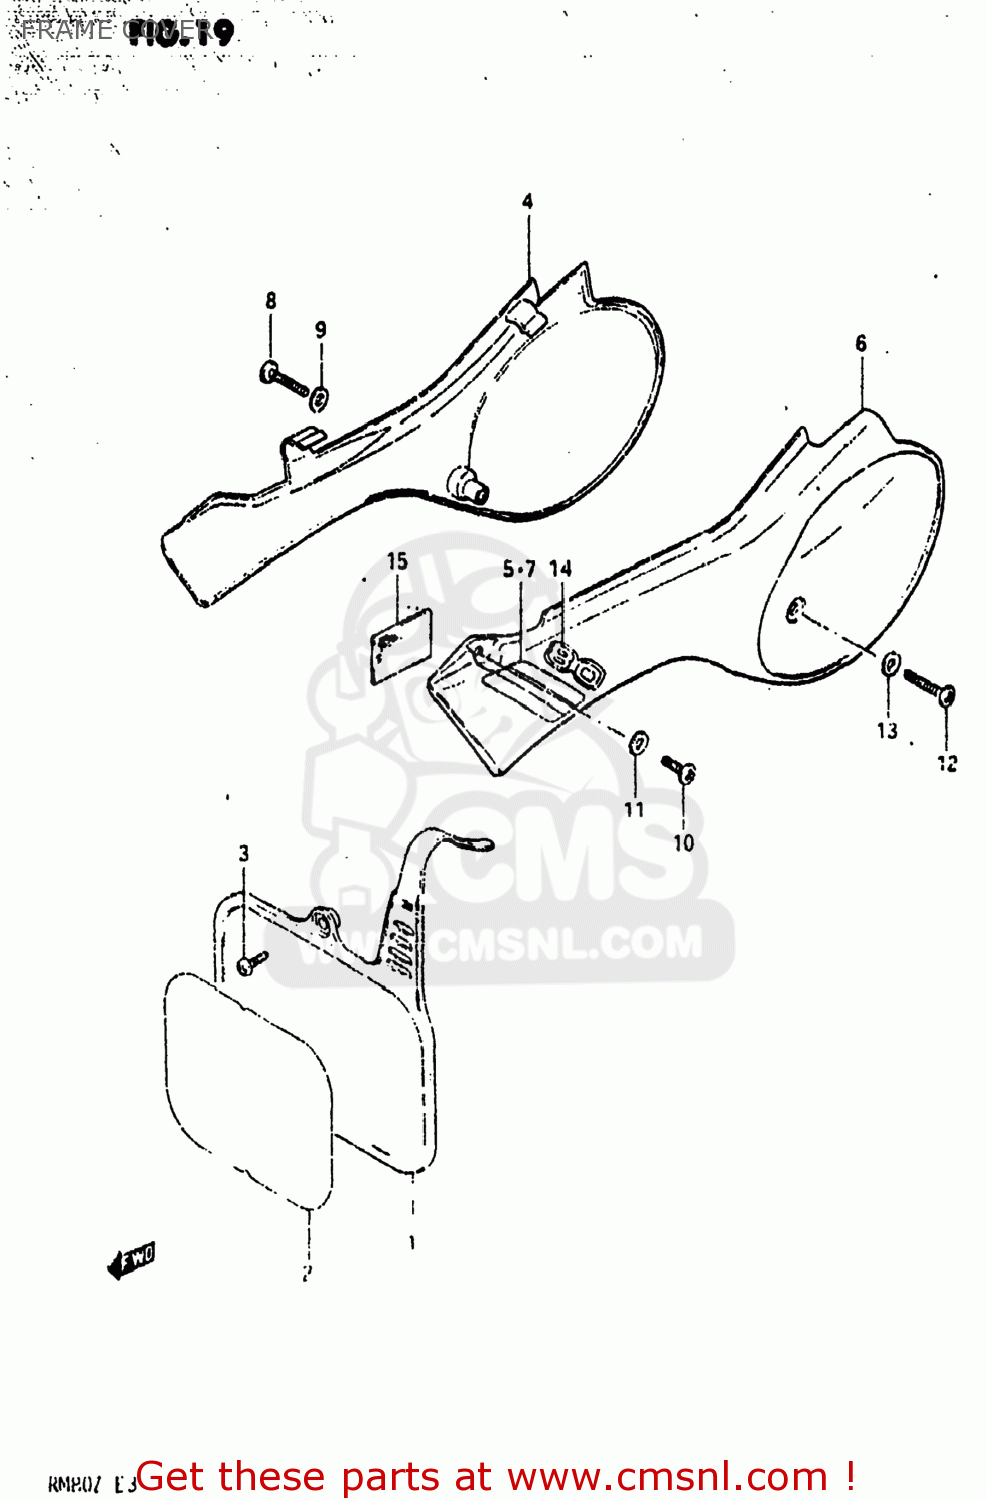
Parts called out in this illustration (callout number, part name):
1	PLATE,NUMBER,FRONT
2	EMBLEM,FRONT NUMBER PLATE
3	SCREW
4	COVER,FRAME,RIGHT
5	TAPE,FRAME COVER,RIGHT
6	COVER,FRAME,LEFT
7	TAPE,FRAME COVER
8	SCREW
9	WASHER
10	SCREW
11	WASHER(6.5X16X1.2)
12	SCREW
13	WASHER
14	EMBLEM
15	HEAT SHIELD,FRAME COVER
